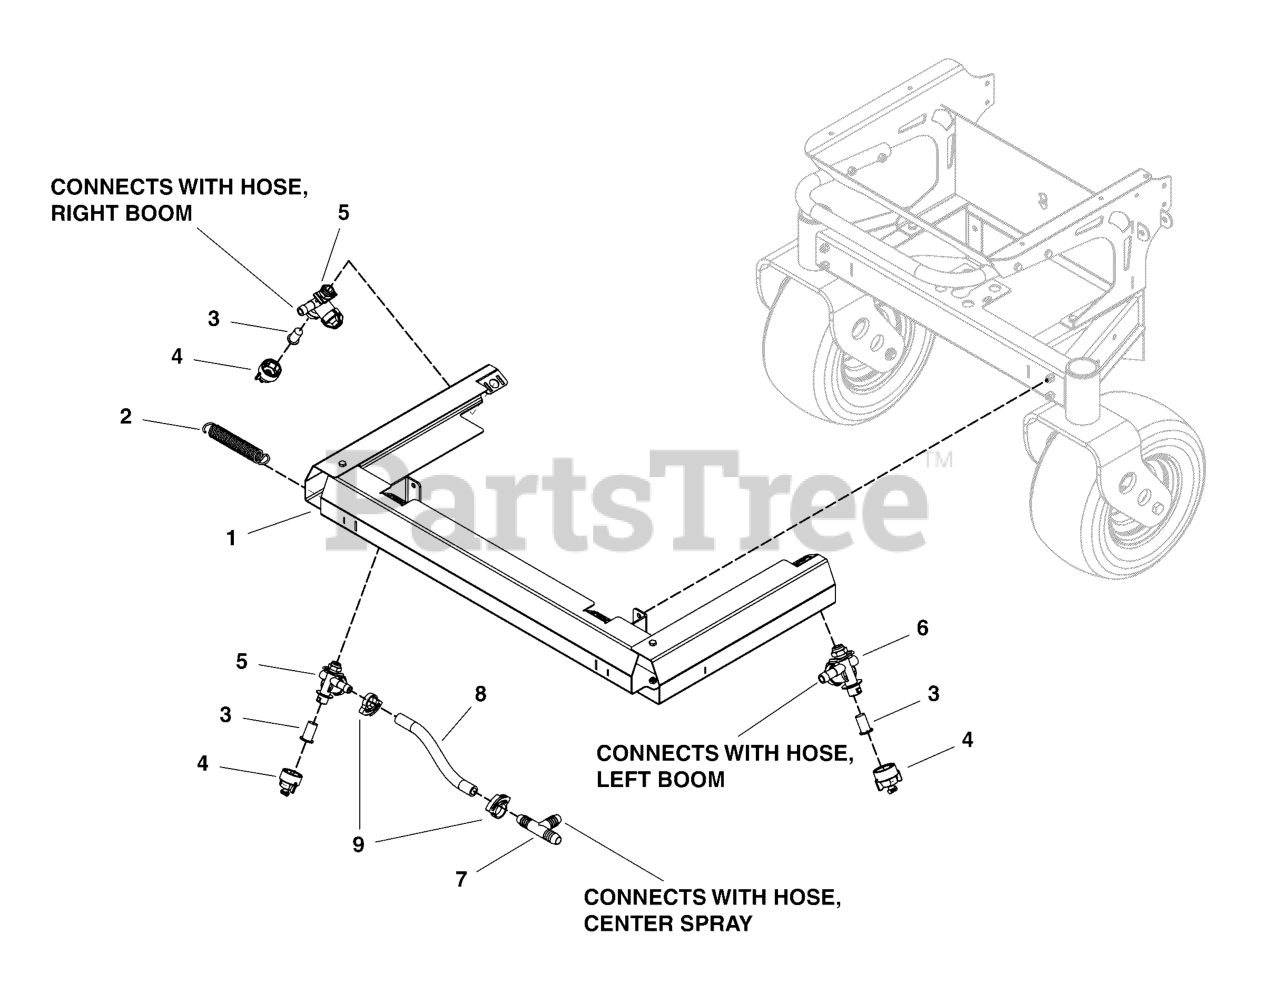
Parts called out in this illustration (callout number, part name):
1	ASM, SPRAY BAR , FOLDING BOOMS
2	SPRING, EXTENSION .64" OD X 4.00" LG SS
3	STRAINER, 50 MESH, POLYPROPYLENE TIP
4	NOZZLE, TIP, WIDE ANGLE, .03 ORIFICE
4	TIP, NOZZLE AIXR 110025 VIOLET
5	DIAPHRAGM CHECK VALVE, RIGHT
6	DIAPHRAGM CHECK VALVE, LEFT
7	FITTING, TEE, 1/2" MPT
8	HOSE, NOZZLE SUPPLY, 0.5" ID, 8.75" LONG
8	HOSE, CHEM .50" X 9"
9	SNAP GRIP CLAMP .656 - .750 ID
9	CLAMP, PINCH 19.8mm TO 22.6mm
10	SCR-CAP, HEX .3125"-18 X .750" SS188
